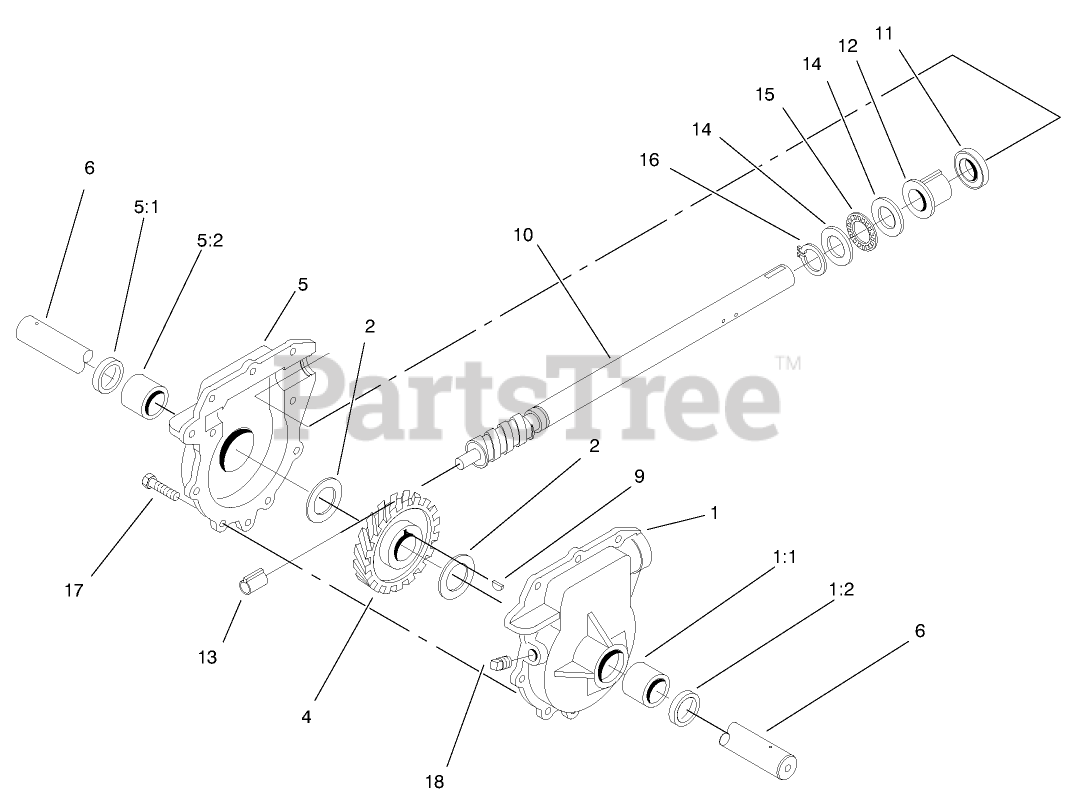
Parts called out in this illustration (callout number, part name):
1:1	BUSHING
1:2	SEAL-OIL
2	WASHER-THRUST
4	GEAR-HELICAL
5:1	SEAL-OIL
5:2	BUSHING
6	SHAFT-AUGER
9	KEY-WOODRUFF
10	SHAFT-IMPELLER
11	SEAL-OIL
12	BUSHING-INPUT
13	BUSHING-WORM
14	WASHER-THRUST
15	BEARING-THRUST
16	RING-RETAINING, EXT
17	SCREW-HWH
18	PLUG-PIPE, SQH
